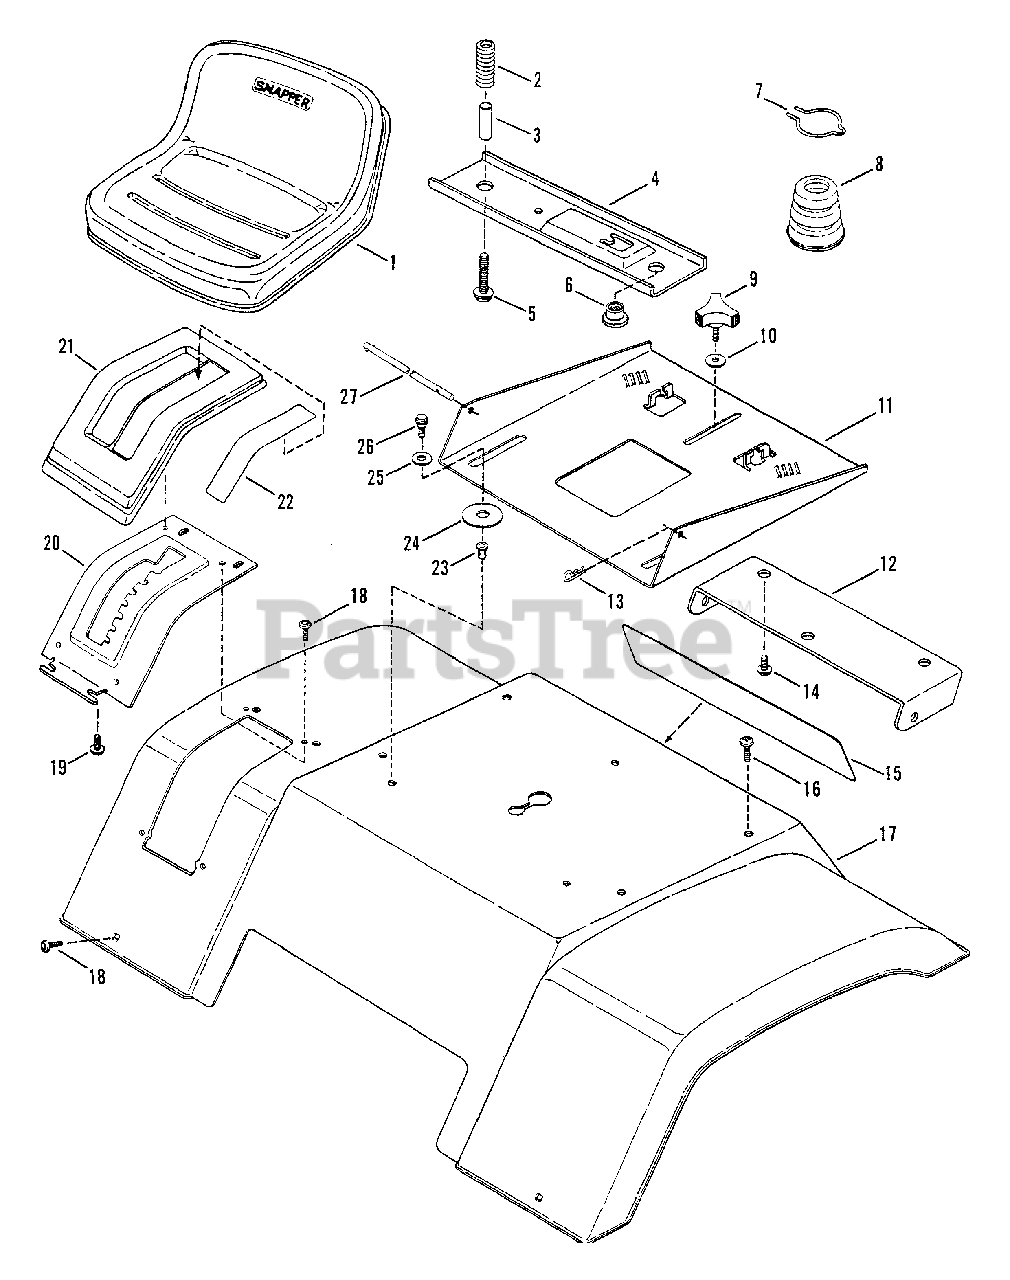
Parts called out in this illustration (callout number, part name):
1	SEAT, Operator's
2	SPRING, Seat Switch
3	SPACER, Seat
4	HOLDER, Seat Switch
5	BOLT, 5/16-18 x 2" Hex Flange Lock
6	BUSHING, Seat
7	CLIP, Seat Bumper
8	CUSHION, Seat
9	KNOB, Seat Adjustment
10	WASHER, 5/16 x 1" Flat
11	SUPPORT, Seat
12	BRACKET, Seat Support
13	PIN, 1/4 Hair
14	BOLT, 5/16-18 x 1/2" Hex Flange Lock
15	DECAL, SNAPPER, Molded Logo
16	SCREW, 5/16-18 x 7/8" Self-Tapping (Torx)
17	FENDER, Rear
18	SCREW, 1/4-20 x 5/8" Self-Tapping (Torx)
19	SCREW, #10-16 x 1/2" Self-Tapping
20	DETENT, Shift
21	COVER, Shift Detent
22	DECAL, Shift Cover
23	RIV-NUT, 5/16-18 Hex
24	SPACER
25	WASHER, 7/16 x 1" Dia. Flat
26	BOLT, 5/16-18 x 3/4" Shoulder
27	ROD, Seat Hinge
